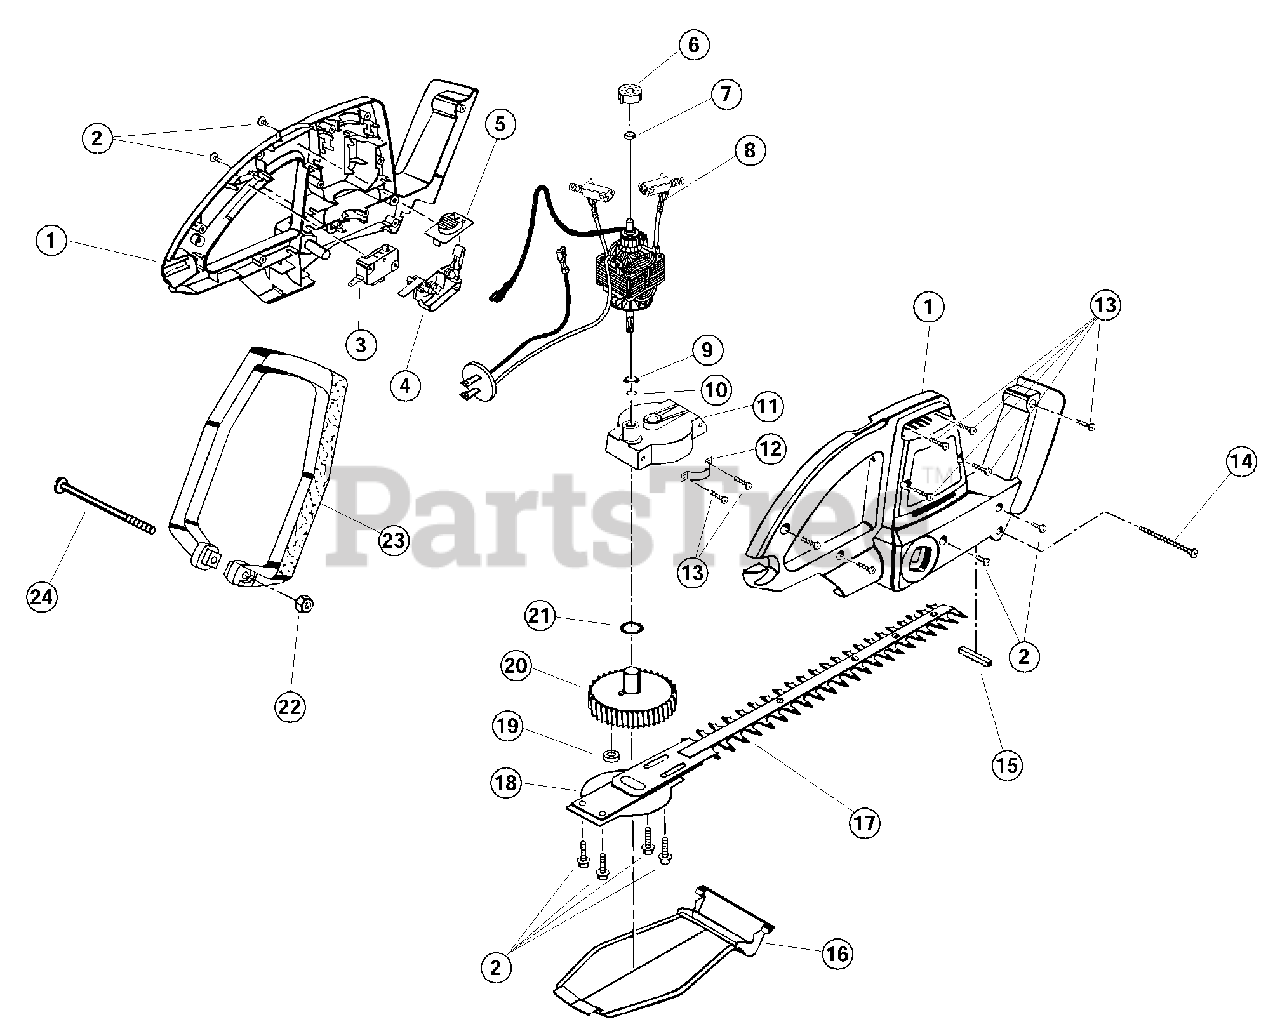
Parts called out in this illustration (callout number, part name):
1	Housing Assembly
4	Switch Trigger Assembly
5	Lock-On Button
6	Sleeve Bearing
8	Motor Assembly
9	Spring Washer
11	Gear Housing w/Bearings
12	Bearing Strap
15	Blade Seal
16	Blade Cover
17	Blade Assembly
18	Grease Cover
19	Drive Washer
20	Gear Assembly (HT816r)
22	Lock Nut
23	Front Handle
